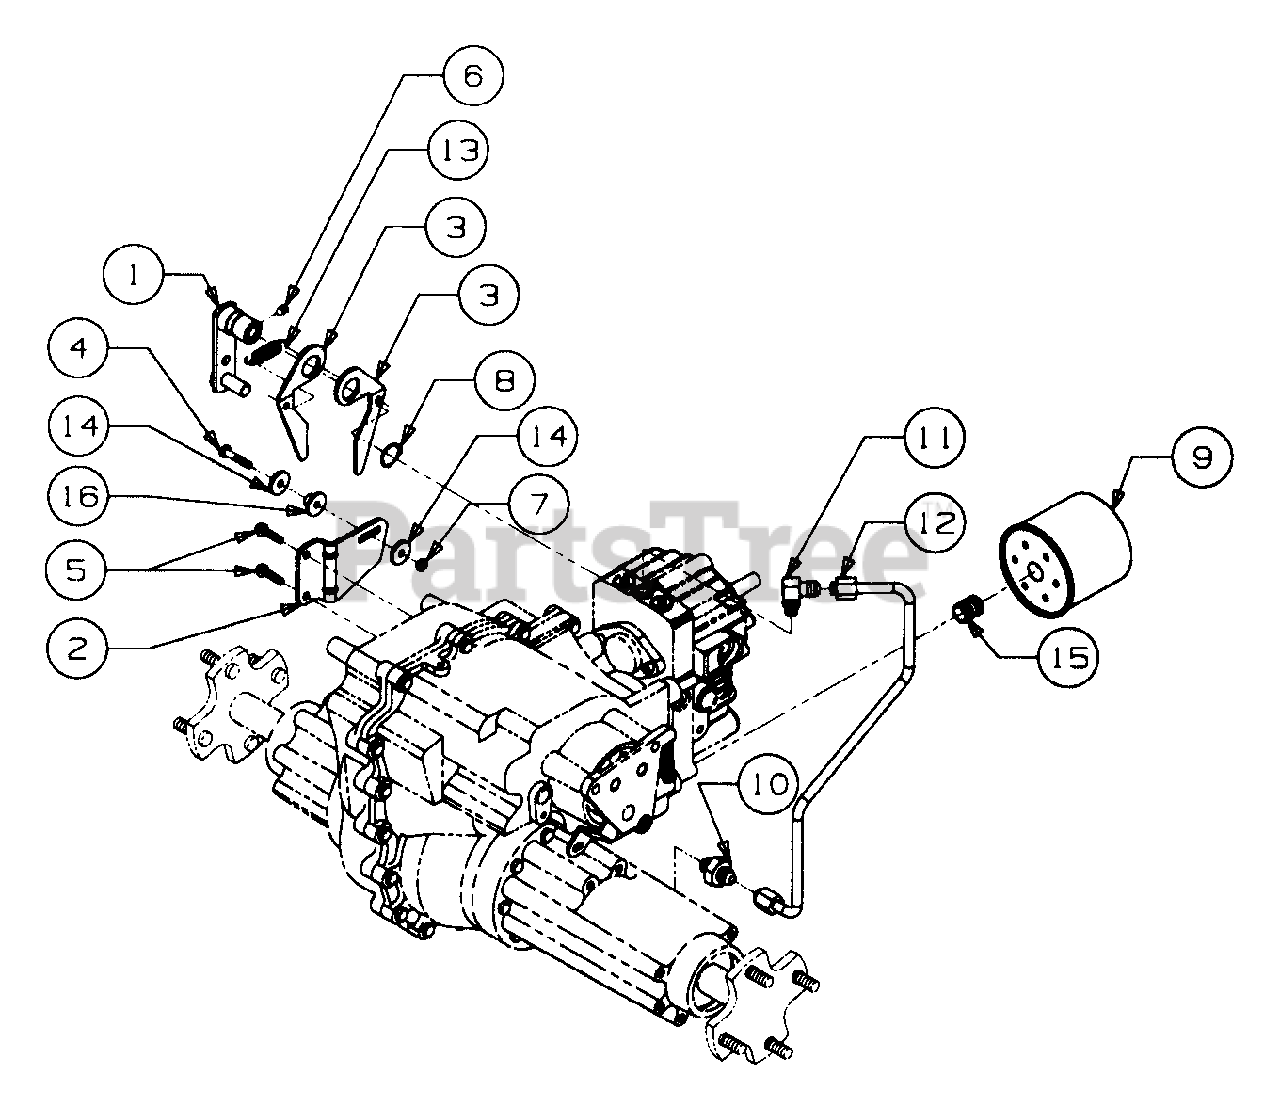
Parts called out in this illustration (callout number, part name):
1	Arm Assembly, Control
2	Bracket, Hydro Neutral
3	Arm, Neutral
4	Screw, Hex Cap, 1/4-20 x 1.25
5	Screw, Hex Wash TT-Tap, 1/4-20 x 1.25
6	Screw w/Patch, Set
7	Nut, Hex Top Lock, 1/4-20
8	Ring, Snap, .875 Shaft
9	Filter, Oil
10	Connector, Tube 37 Deg. w/O-Ring
11	Elbow, Adjustable w/O-Ring
12	Tube, Pickup
13	Spring, Extension, .5 OD x 1.97 Lg
14	Washer, Flat, .25 x .93 x .120 Thk
15	Nipple, Oil Filter
16	Spacer, Centering
